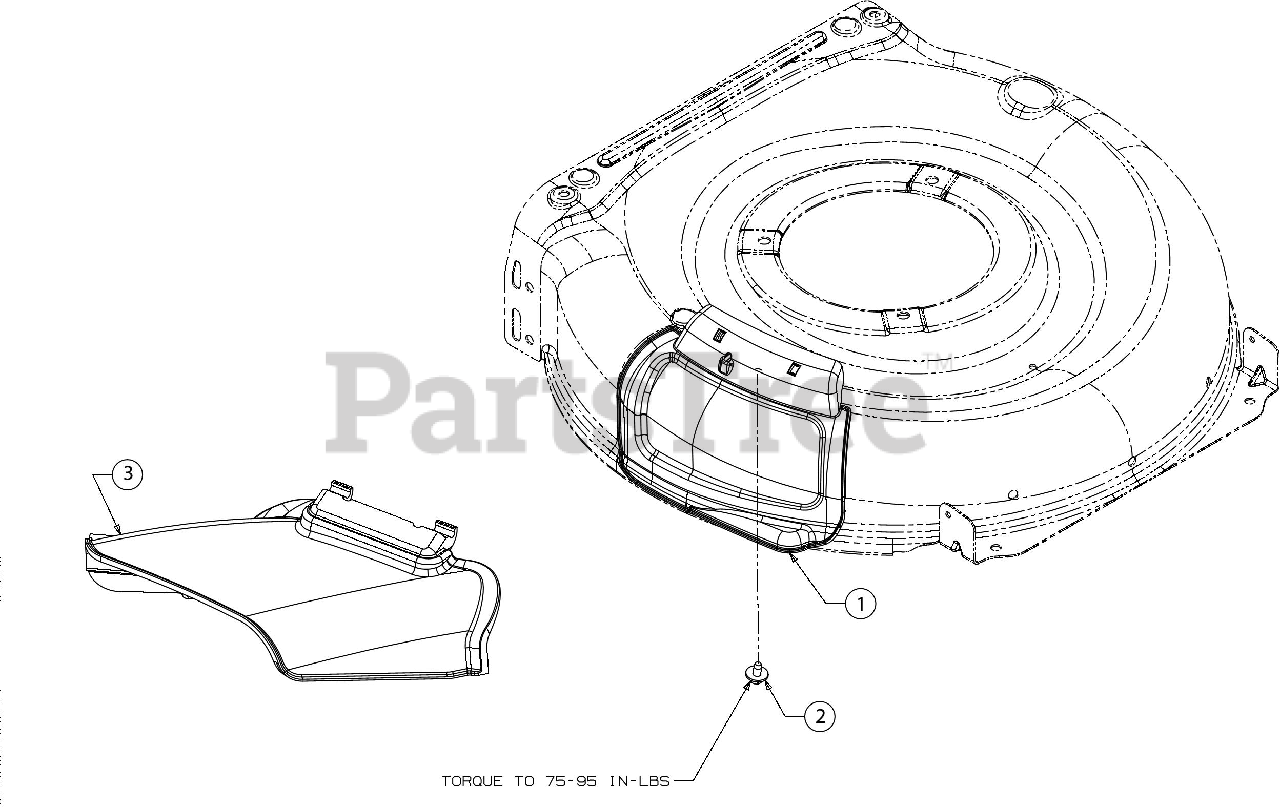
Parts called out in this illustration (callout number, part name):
1	HINGED MULCH PLUG ASSEMBLY
2	SCREW 1/4-20 X .50
3	SIDE DISCHARGE CHUTE
